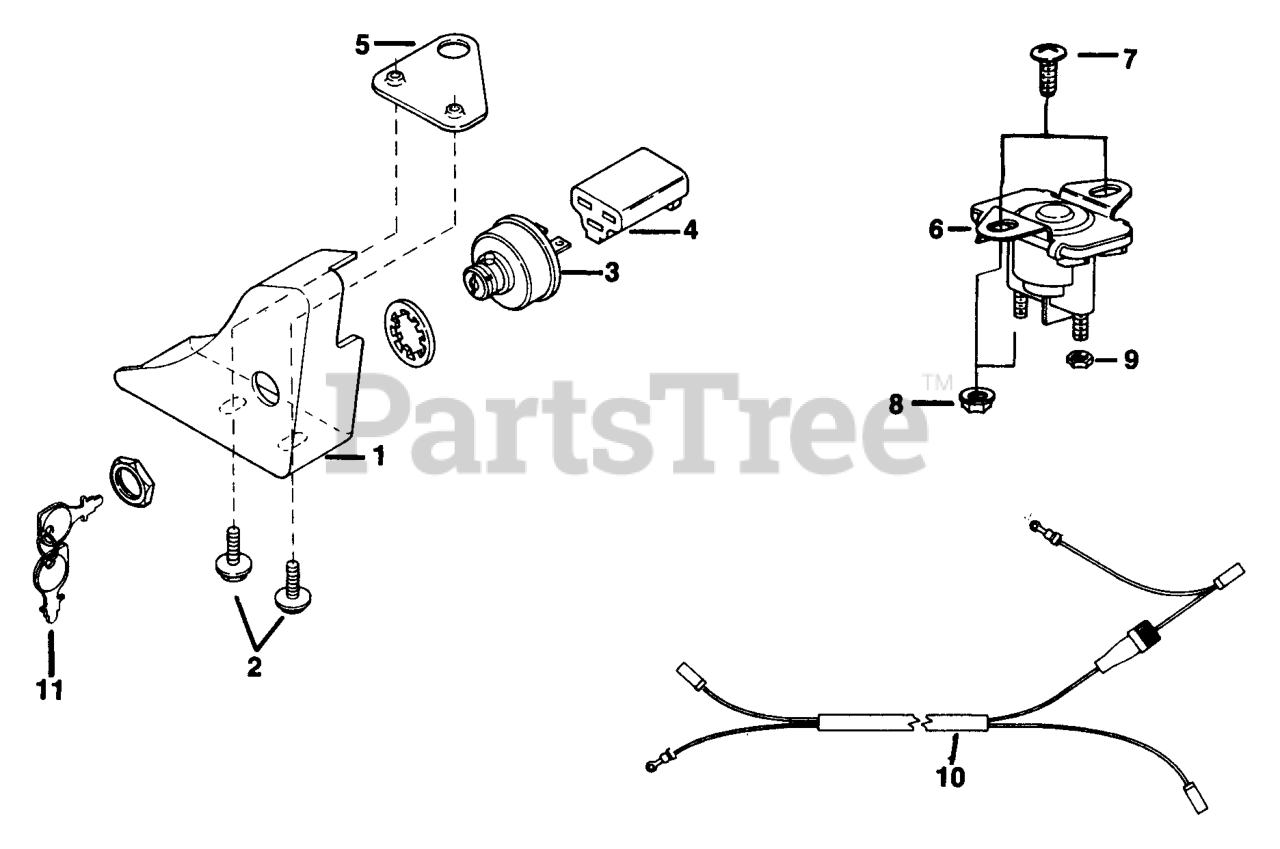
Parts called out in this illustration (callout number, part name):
3	SWITCH, ASSEMBLY, KEY
6	SOLENOD - USE 25 435 01
8	PALNUT, 1/4-20
9	NUT, 1/4-20 GRADE 2 USE 25 100 20-S
10	HARNESS - DISCONTINUED
11	KEY, SET -USE 48 340 01-S
